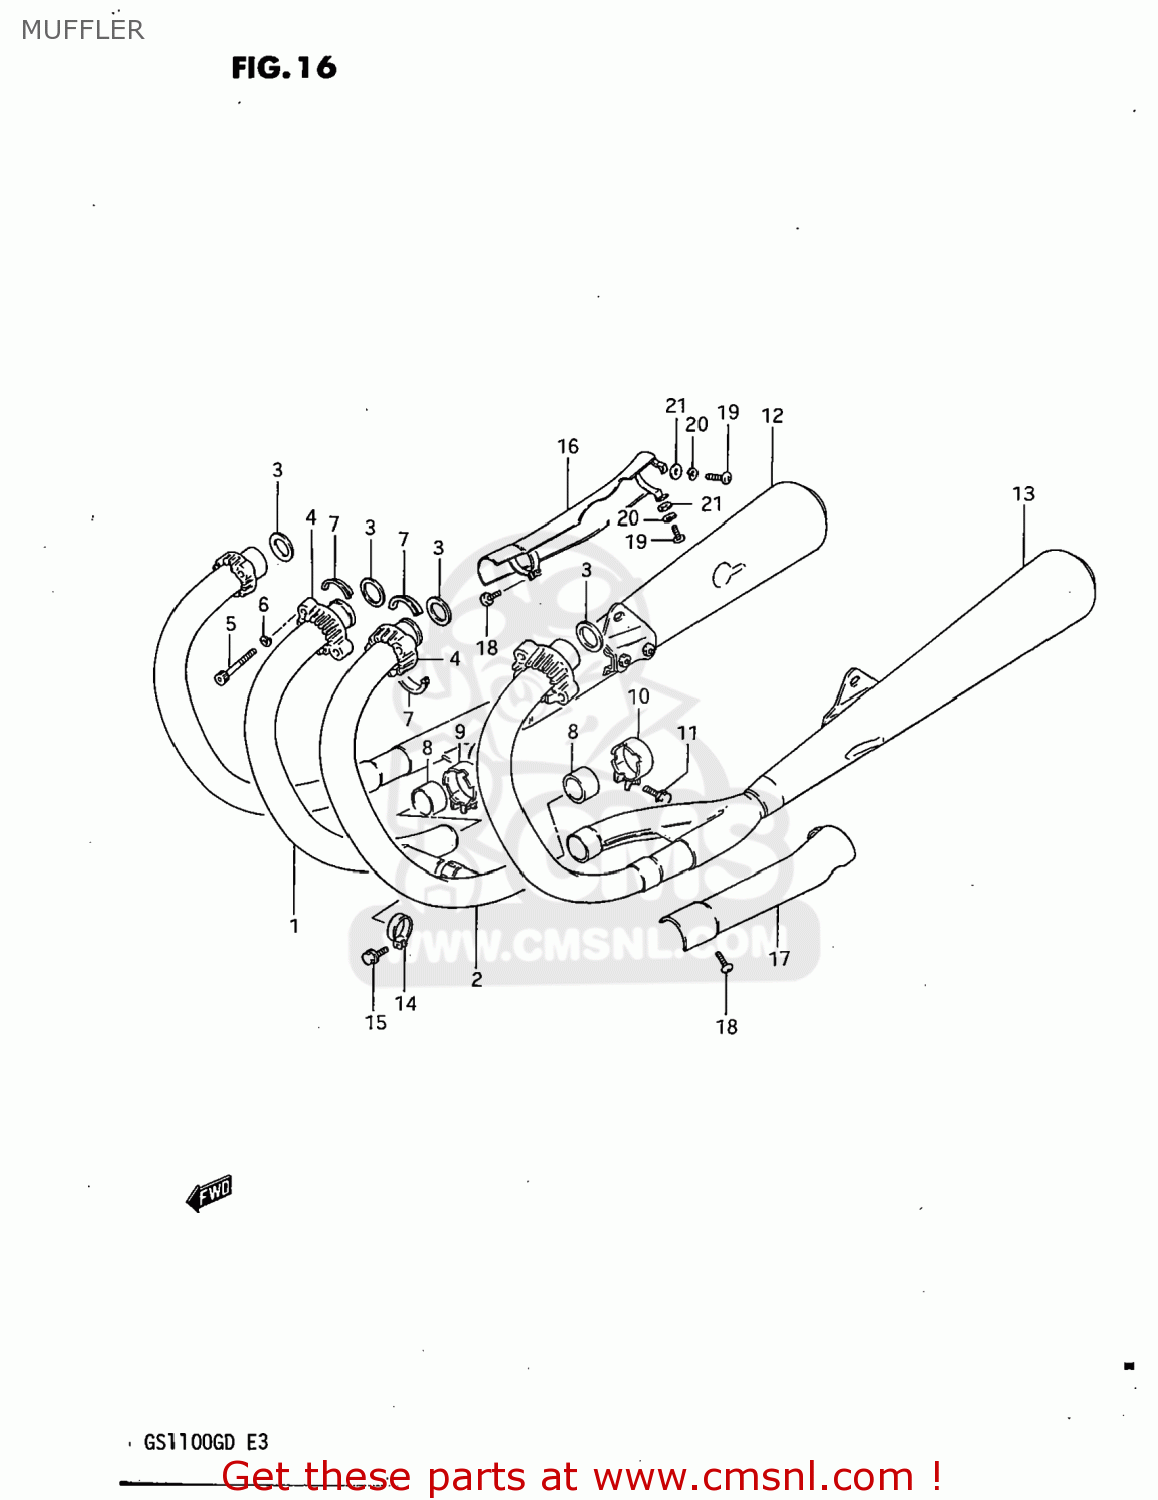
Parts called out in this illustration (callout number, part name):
1	PIPE,CENTER EXHAUST
2	COVER,EXHAUST PIPE
3	GASKET,EXHAUST PIPE (NAS)
4	CLAMP(H:21)
5	BOLT
6	LOCK WASHER
7	PLATE,EXHAUST
8	CONNECTOR,MUFFLER
9	CLAMP,MUFFLER CONNECTOR,R
10	CLAMP,MUFFLER CONNECTOR,L
11	BOLT
12	MUFFLER ASSEMBLY
13	MUFFLER ASSEMBLY
14	CLAMP
15	BOLT
16	COVER,MUFFLER,RIGHT
17	COVER,MUFFLER,LEFT
18	SCREW
19	SCREW
20	LOCK WASHER
21	WASHER
